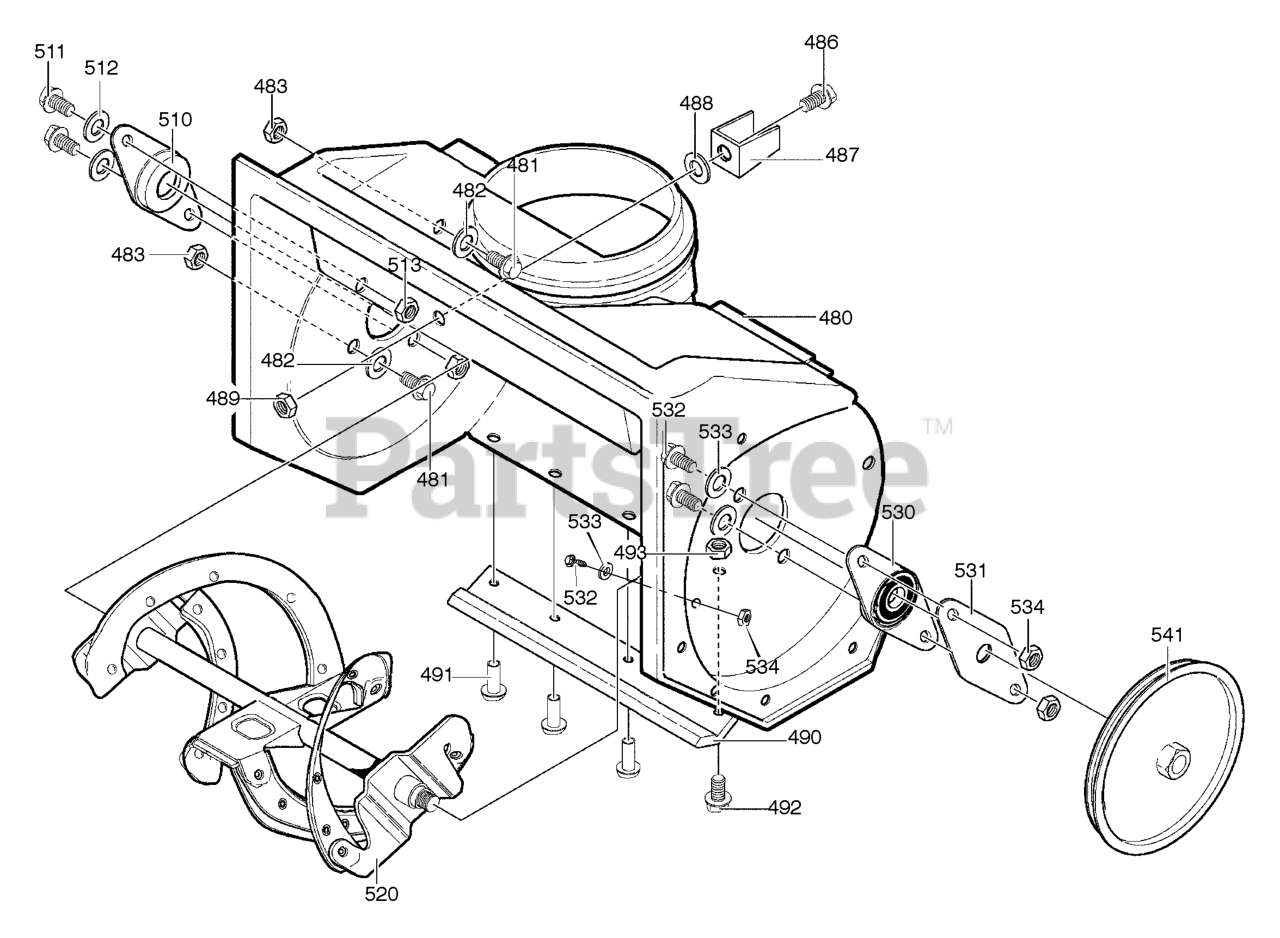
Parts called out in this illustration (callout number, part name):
480	HOUSING, ASSY
481	SCREW, 1/4-20X.75
482	WASHER
483	NUT, 1/4-20
486	SCREW, 1/4-20X.63
487	BRACKET, STOP
488	WASHER, FLAT
489	NUT, 1/4-20
490	BLADE, SCRAPER
492	SCREW, 1/4-20X.75
493	NUT, 1/4-20
510	BEARING, FLANGE
511	SCREW, 1/4-20X1.00
512	WASHER, FLAT
513	NUT, 1/4-20
520	AUGER, ASSY
530	BEARING & PLATE ASSEMBLY
531	PLATE, RETAINER
532	SCREW, 1/4-20X.63
533	WASHER, FLAT
534	NUT, 1/4-20 REGHEXCTRLK
541	PULLEY, V3L 6.00
